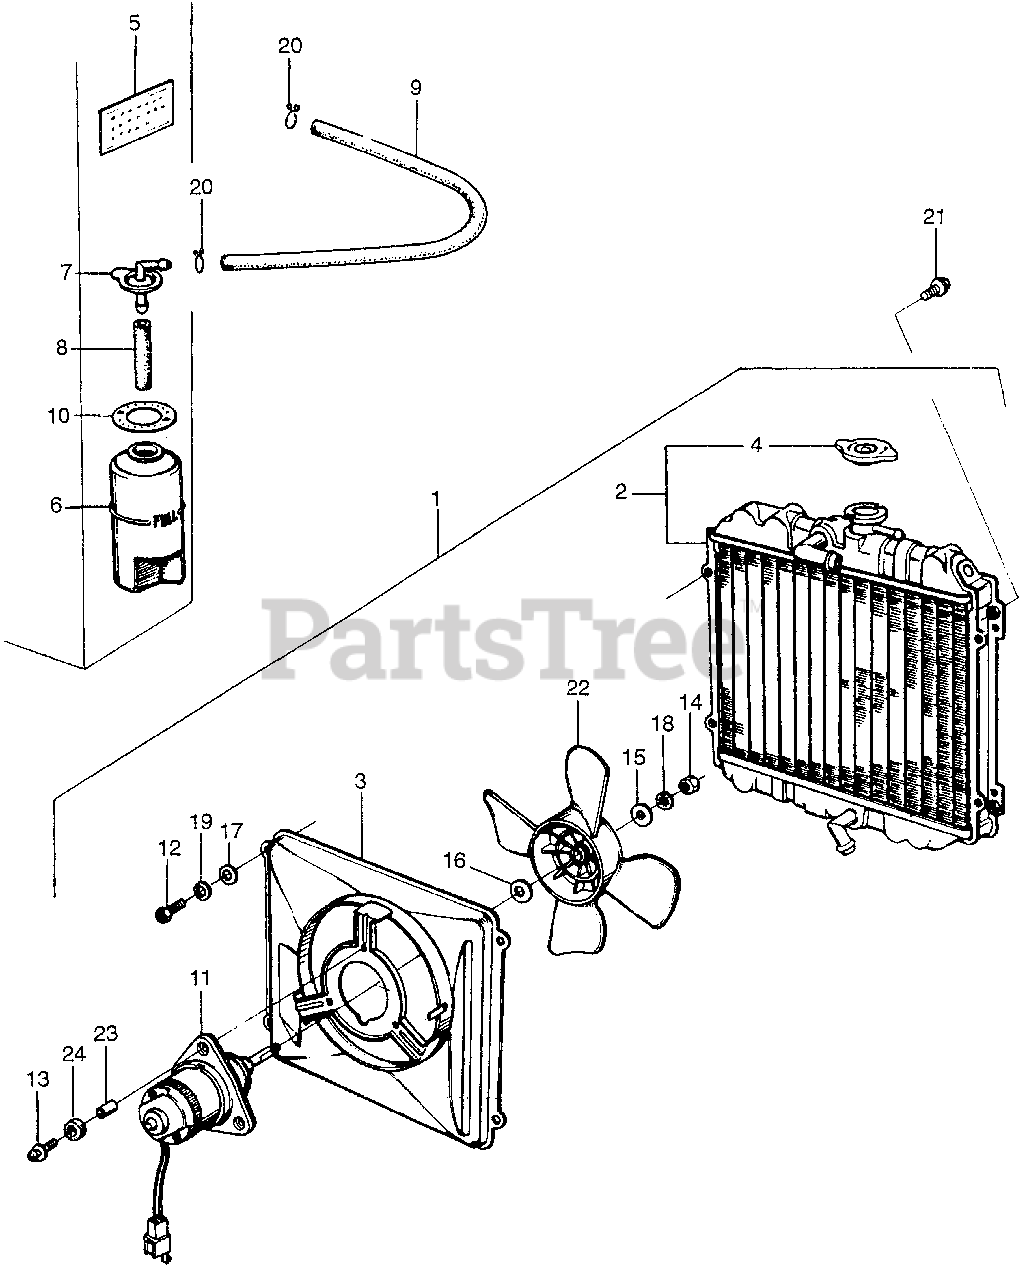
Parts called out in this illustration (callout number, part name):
1	RADIATOR ASSY.
3	SHROUD, RADIATOR
4	CAP (NOT AVAILABLE)
5	LABEL, RADIATOR CAUTION (NOT AVAILABLE)
6	TANK, RESERVOIR
7	CAP, RESERVOIR TANK
8	HOSE B, RESERVE
9	TUBE, RESERVE
10	MARK, RESERVE TANK (NOT AVAILABLE)
11	MOTOR, COOLING FAN (DENSO)
11	MOTOR, FAN
12	BOLT, HEX. (6X20)
13	SCREW, PAN (4X18)
14	NUT, HEX. (5MM)
15	WASHER, PLAIN (5MM)
16	WASHER, PLAIN (6MM)
17	WASHER, PLAIN (6MM)
18	WASHER, SPRING (5MM)
19	WASHER, SPRING (6MM)
20	CLIP, TUBE (C11)
21	BOLT, FLANGE (6X12)
22	FAN, COOLING
23	COLLAR (DENSO)
24	RUBBER, BUSHING (DENSO)
